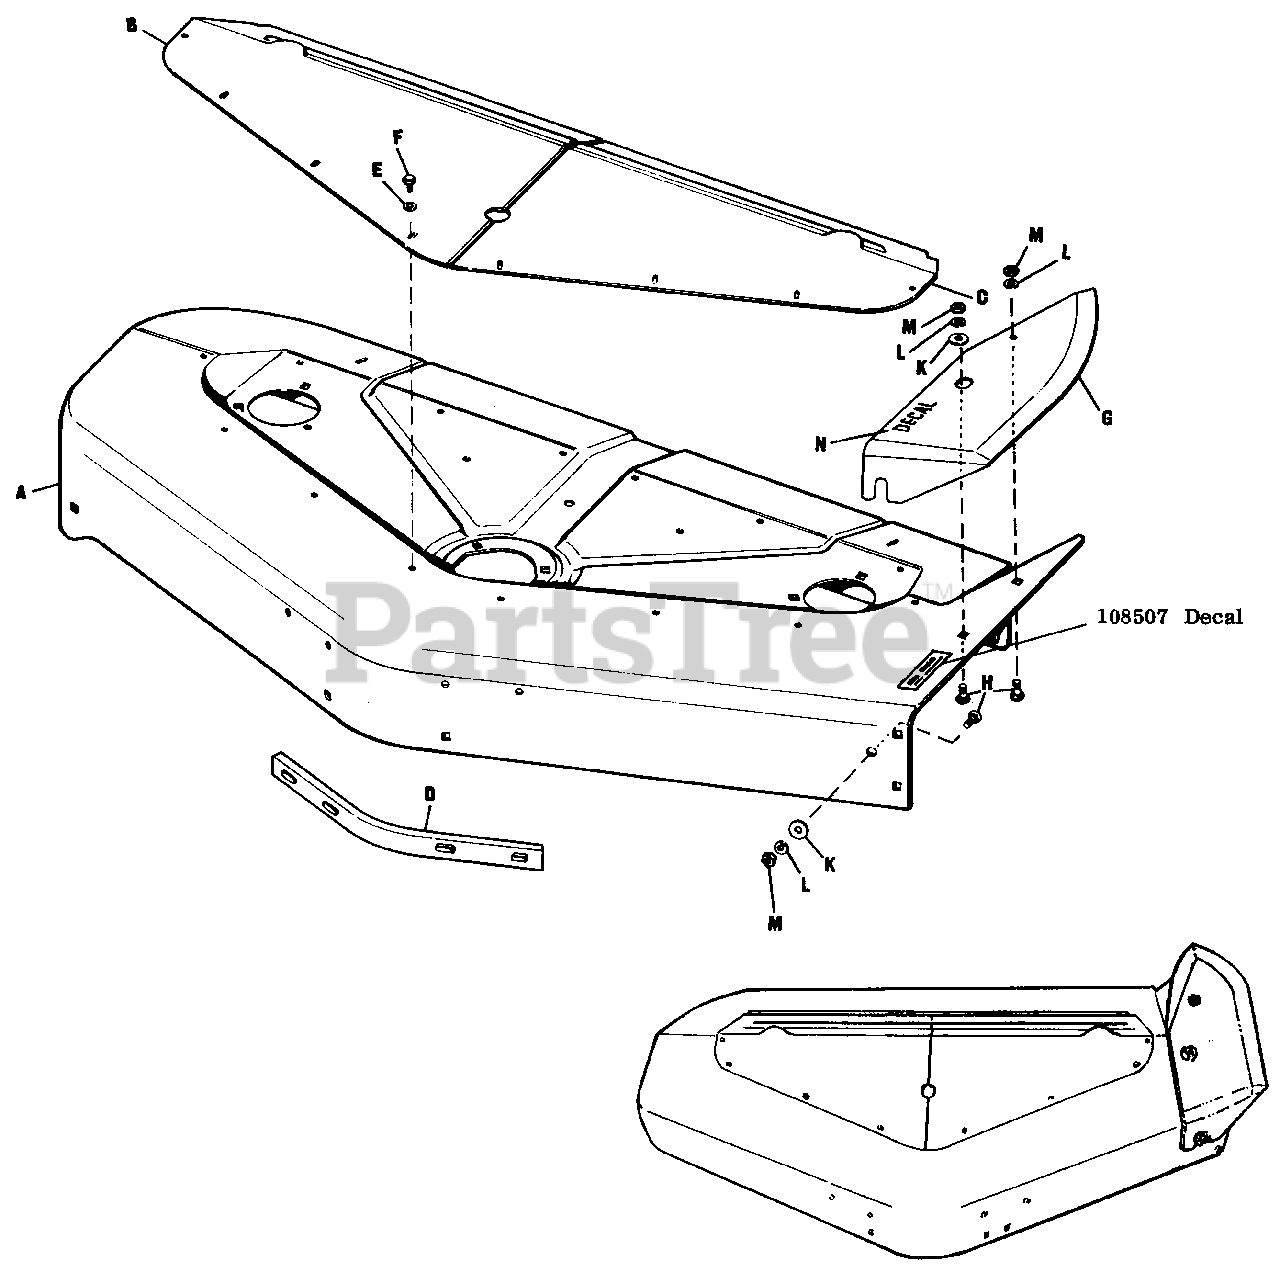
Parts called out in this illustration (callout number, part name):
A	Mower Housing
B	R.H. Cover
C	L.H. Cover
D	Reinforcing Bar
E	Plain Washer
F	Self Tapping Screw, 1/4"-20 x 3/8" lg.
G	Deflector
H	Carriage Bolt, 3/8"-16 x 3/4" lg.
K	Special Washer
L	Lock Washer, 3/8"
M	Hex Nut, 3/8"-16
